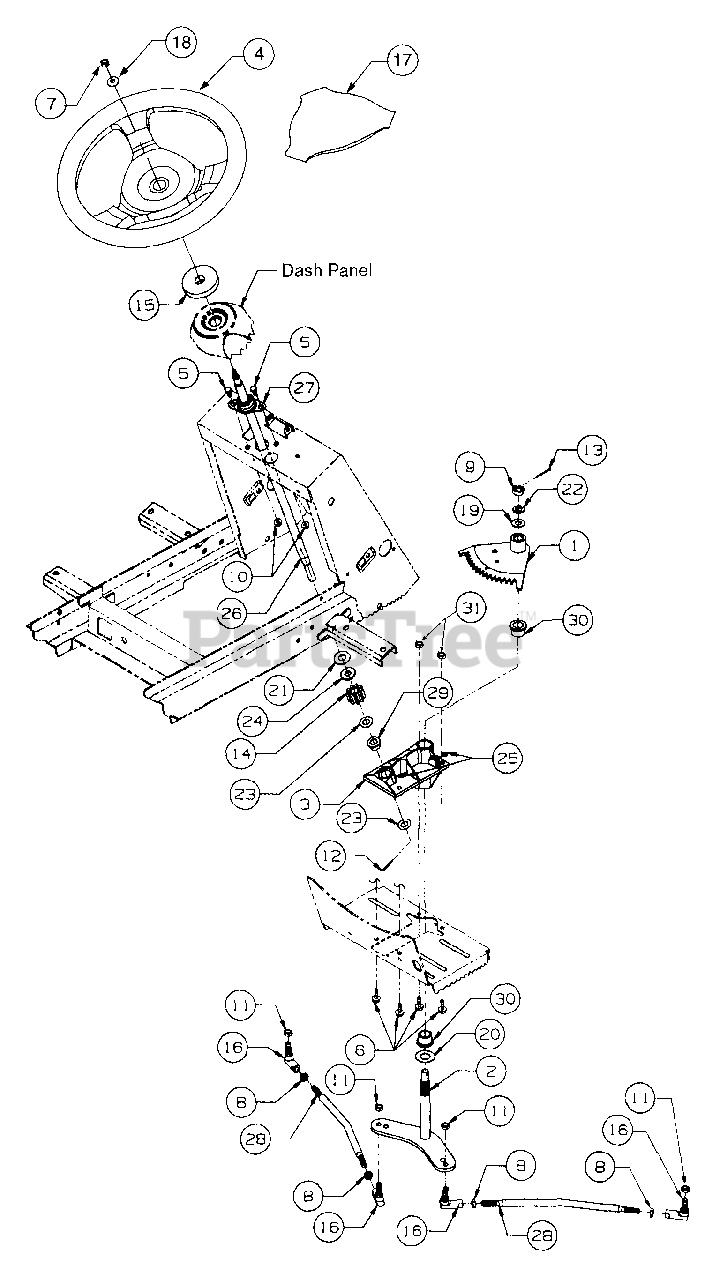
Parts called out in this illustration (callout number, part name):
1	Segment Assy, 18T Steering
2	Arm Assy, Lower Steering
3	Housing Assy
4	Steering Wheel, Soft Grip
5	Screw, Hex Cap, 1/4 - 20 x .62, GR5
6	Screw, Hex Hd Cap, 5/16-18 x 1 GR5
7	Nut, Hex Center Lock, 5/16-18
8	Nut, Jam, 3/8-24 GR2
9	Nut, Hex Slotted, 1/2-20 GR5
10	Nut, Hex Flange Lock, 1/4-20
11	Nut, Hex Lock, 3/8-24 GR5
12	Pin, Cotter, 1/8 Dia x 1
13	Pin, Cotter, 3/32 Dia x 1.25
14	Pinion, Steering
15	Gasket, Steering
16	Joint, Ball, 3/8-24
17	Insert, Steering Wheel
18	Washer, Bell, .340 x .88 x .06 Thk
19	Washer, Flat, .510 x 1 x .06 Thk
20	Washer, Flat, .760 x 1.5 x .03 Thk
21	Washer, Flat, .56 x 1 x .04 Thk
22	Washer, Lock, 1/2
23	Washer, Flat, .531 x 1 x .027 Thk
24	Wshr, Rubber Flat, .50x1.12x.125 Thk
25	Fitting, Grease, 3/16 Drive Type
26	Shaft, Steering
27	Bearing, Flange
29	Bearing, Flange, .503 ID
30	Bearing, Bronze Flange, .75 ID
31	Nut, Hex Center Lock, 5/16-18
